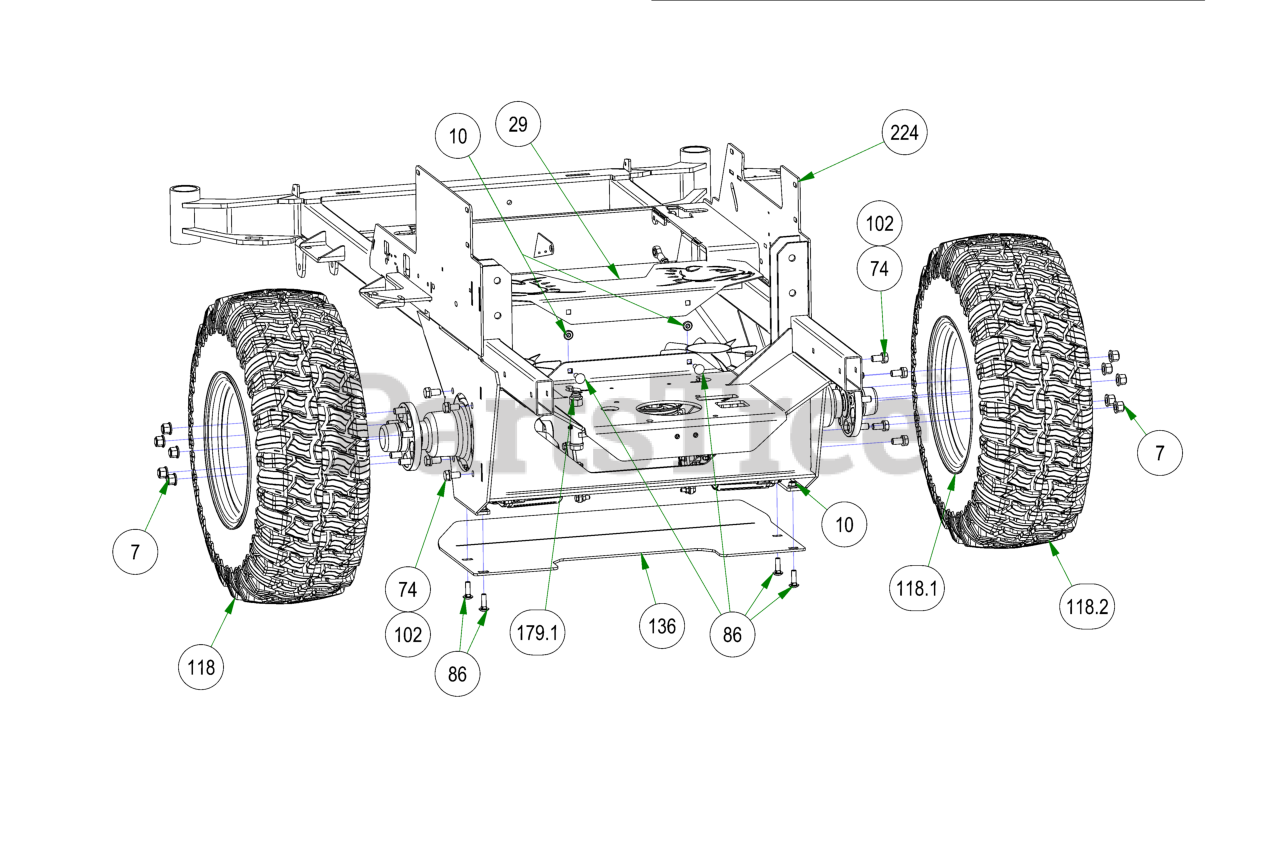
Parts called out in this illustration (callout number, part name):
7	Acorn Lug Nut
8	3/8-16 NYLON INSERT LOCKNUT ZINC
10	3/8-16 NYLON INSERT FLANGE LOCKNUT (GR.F) ZINC
14	1/2-13 HEX NUT ZINC
17	5/16-18 NYLON INSERT FLANGE LOCKNUT ZINC
29	2019 Rigid Fan Guard
67	All Thread
68	5/16-18 X 1-1/4 HEX C/S (GR.5) ZC
69	5/16-18 X 1 HEX CAP SCREW (GR.5) ZINC
74	1/2-13 X 1 HEX CAP SCREW (GR.5) ZINC
79	1/2-13 NYLON INSERT JAM LOCKNUT ZINC
85	3/8-16 X 1-1/4 HEX CAP SCREW (GR.5) ZINC
86	3/8-16 X 1-1/4 CARRIAGE BOLT ZINC
102	1/2 SPLIT LOCKWASHER (GR.8) ZINC/YELLOW
118	24x12-12 Reaper Turf Tire & Wheel Assembly
118.1	12x12" Black Wheel For 2015 Outlaw
118.2	24x12-12 Reaper Turf Tire
125	Drive Arm Transaxle Spacer
136	2019 Outlaw Rigid Skid Plate
167	Deck spring big diameter
168	2019 Rebel Push Rod Assembly
168.1	5/16 LH Nut
168.2	3/8-24 HEX NUT ZINC YELLOW
168.3	2019 Rebel Push Rod
168.4	Spherical Rod End - Outlaw
168.5	Spherical Rod End - Outlaw
176	2015 Outlaw Brake Adapter (4400 Transaxles Only)
179	2019 Rebel Pump Idler
179.1	5/8-11 NYLON INSERT JAM LOCKNUT ZINC
179.2	1/2-13 NYLON INSERT FLANGE LOCKNUT ZINC
179.3	5/8-11 X 4-1/2 HEX CAP SCREW (GR.5) ZINC
179.4	1/2-13 X 2-3/4 HEX CAP SCREW (GR.5) ZINC
179.5	.635 ID X 1.120 OD X .140 THICK FLAT WASHER NYLON
179.6	5/8 SOLID SHAFT COLLAR (W/1 SET SCREW) ZINC
179.7	1/2 SOLID SHAFT COLLAR (W/1 SET SCREW) ZINC
179.8	4 3/4" Idler Pulley
179.9	Deck Idler
185	2019 Rebel Pump Belt
195	4400 Transaxle-Left-Base Outlaw/2019 Rebel
195.1	Gold Transaxle Spring
195.2	Fan/Pulley Kit for 4400 Outlaw
195.3	Hub for 4400 Transaxle
195.4	Seal Kit for 4400 Series Outlaw Transaxle
195.5	Hydro Filter for 4400 Transaxle
196	4400 Transaxle-Right-Base Outlaw/2019 Rebel
196.1	Gold Transaxle Spring
196.2	Fan/Pulley Kit for 4400 Outlaw
196.3	Hub for 4400 Transaxle
196.4	Seal Kit for 4400 Series Outlaw Transaxle
196.5	Hydro Filter for 4400 Transaxle
224	2023 Rebel Frame - Painted
